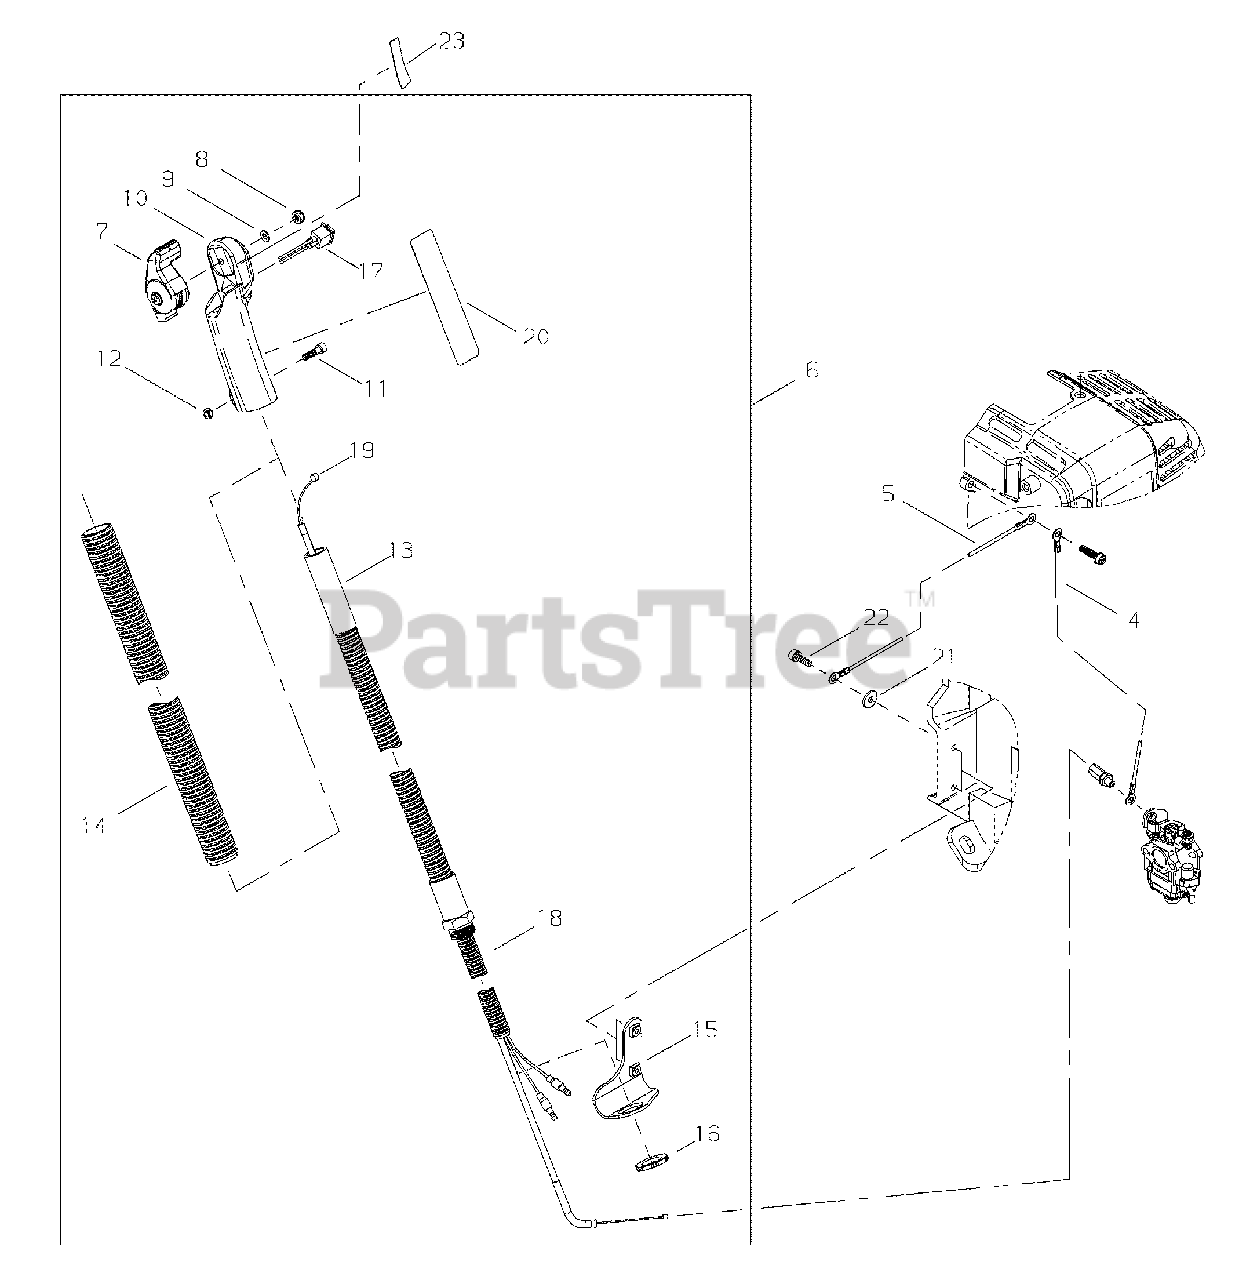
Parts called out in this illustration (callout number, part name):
4	WIRE, STATIC DISCHARGE 110 MM
5	LEAD - GROUND 550 MM
6	THROTTLE CONTROL ASSY
7	CONTROL, THROTTLE
8	U-NUT M5
9	WASHER 5 MM
10	GRIP
11	BOLT M5×16
12	NUT M5
13	ARM, FLEX
14	TUBE, OUTER FLEX
15	BRACKET, MOUNTING
16	NUT
17	SWITCH, ON-OFF
18	TUBE, FLEXIBLE
19	CABLE, THROTTLE
20	PLATE, GROUND
21	WASHER Ø15ר5.2×1.6
22	BOLT, ADHESIVE M5×18
23	LABEL, THROTTLE
